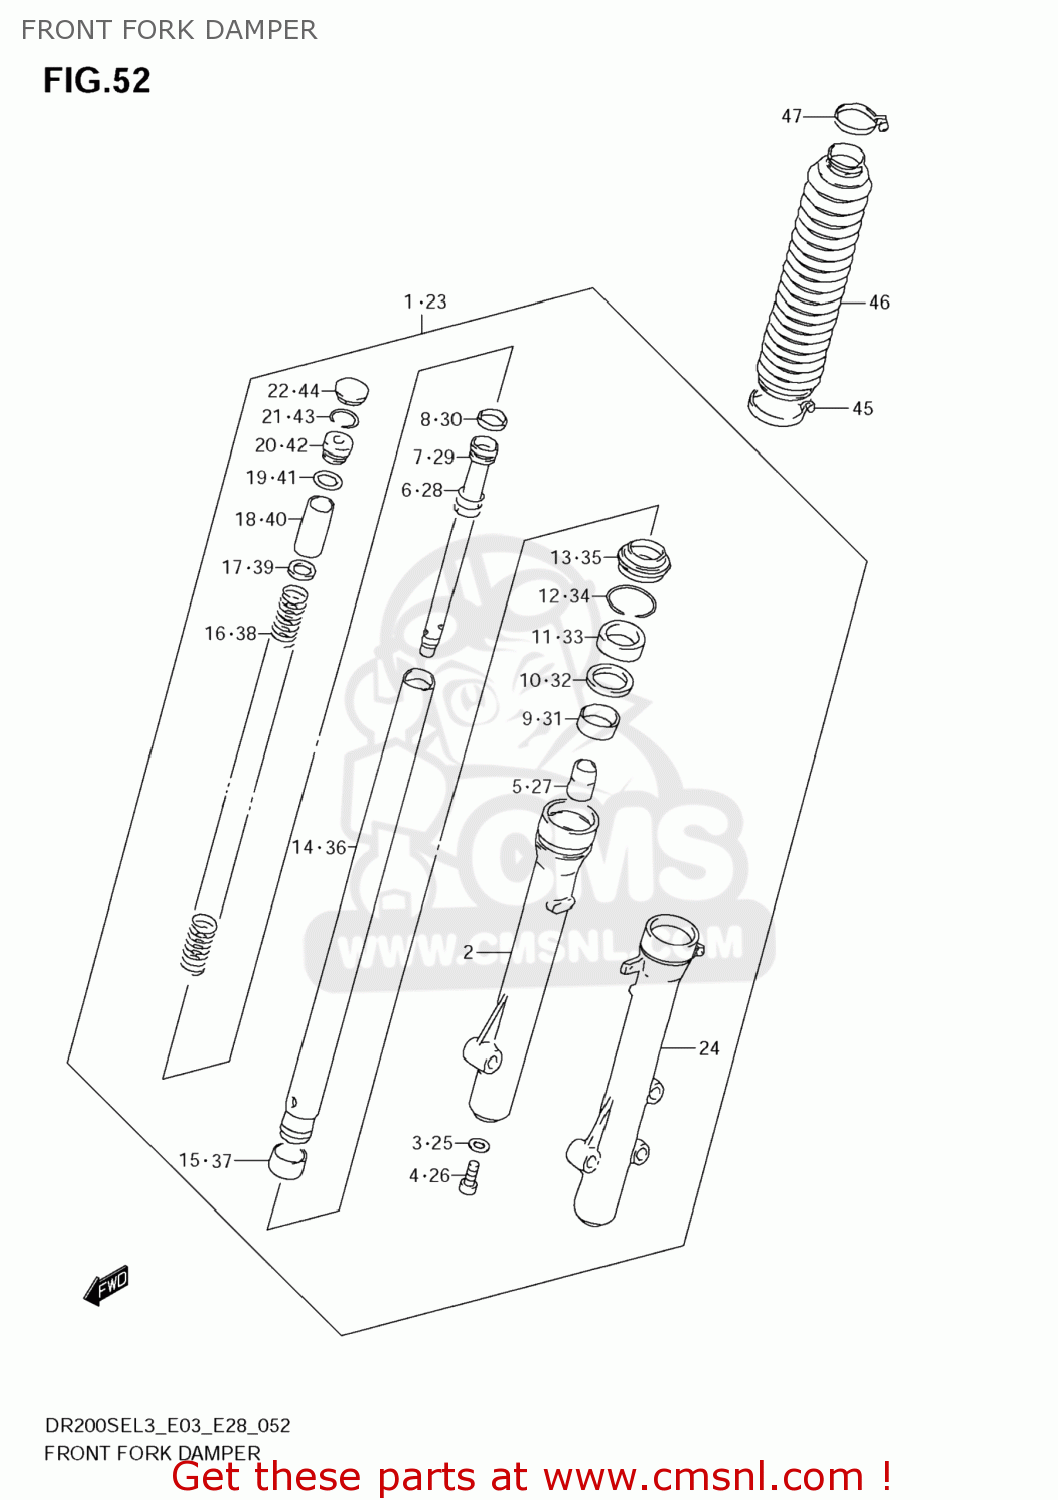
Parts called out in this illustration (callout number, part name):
1	DAMPER ASSY,FR FORK,R
2	TUBE,OUTER,R
3	GASKET (NAS)
4	BOLT
5	PIECE,OIL LOCK
6	SPRING,REBOUND
7	CYLINDER
8	RING,PISTON
9	BUSH,GUIDE
10	SPACER,SEAL
11	SEAL,OIL 35X48X11
12	RING,OIL SEAL STOPPER
13	SEAL,DUST
14	TUBE,INNER
15	PISTON
16	SPRING,MAIN
17	SPRING,JOINT
18	SPACER,SPRING
19	O RING
20	SPRING SEAT B
21	RING,STOPPER
22	CAP
23	DAMPER ASSY,FR FORK,L
24	TUBE,OUTER,L
25	GASKET (NAS)
26	BOLT
27	PIECE,OIL LOCK
28	SPRING,REBOUND
29	CYLINDER
30	RING,PISTON
31	BUSH,GUIDE
32	SPACER,SEAL
33	SEAL,OIL 35X48X11
34	RING,OIL SEAL STOPPER
35	SEAL,DUST
36	TUBE,INNER
37	PISTON
38	SPRING,MAIN
39	SPRING,JOINT
40	SPACER,SPRING
41	O RING
42	SPRING SEAT B
43	RING,STOPPER
44	CAP
45	BAND,BOOT LWR
46	BOOT
47	BAND
